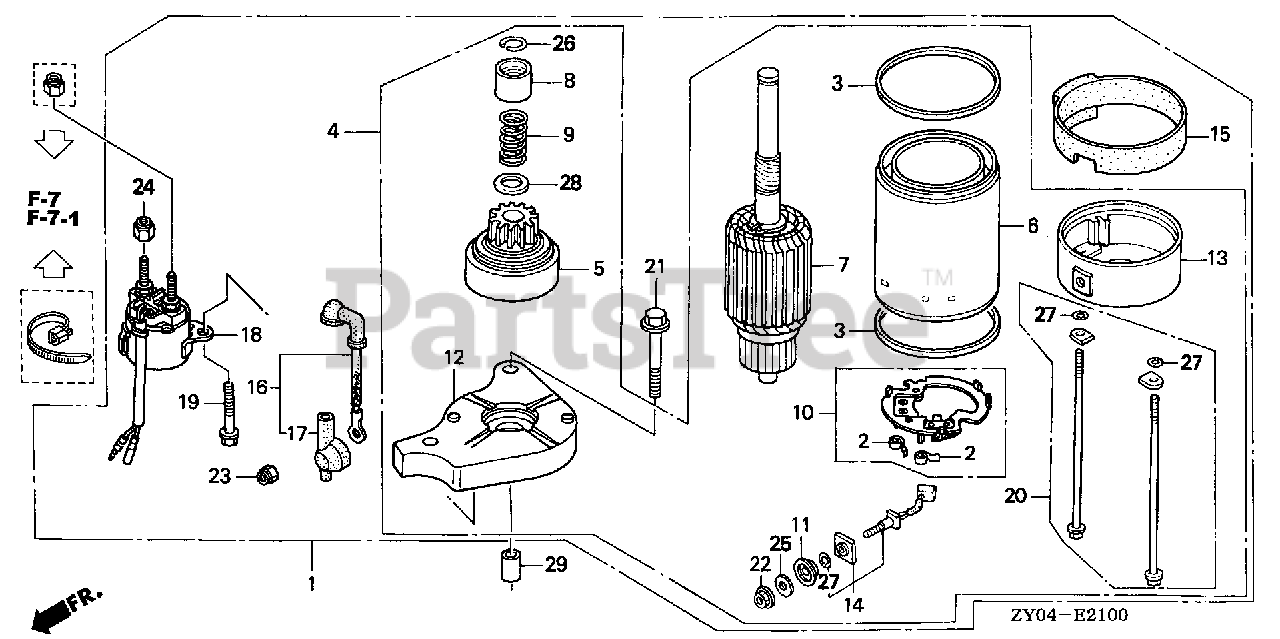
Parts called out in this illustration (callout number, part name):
1	STARTER MOTOR ASSY.
2	SPRING, CARBON BRUSH
4	STARTER MOTOR UNIT
8	PIECE, STOPPER
9	SPRING, RETURN
10	HOLDER, BRUSH
12	BRACKET, FR.
13	BRACKET, RR.
14	TERMINAL UNIT
15	SUSPENSION, STARTER
16	WIRE, MAGNETIC SWITCH
17	COVER, STARTER TERMINAL
18	SWITCH ASSY., STARTER MAGNETIC
19	BOLT, FLANGE (6X14)
20	BOLT SET, SETTING
21	BOLT, FLANGE (8X45)
22	NUT-WASHER (6MM)
23	NUT, LOCK (6MM)
24	NUT, LOCK (6MM)
25	WASHER (6MM)
26	CIRCLIP (14MM)
27	O-RING (4X2)
29	PIN, DOWEL (10X12)
